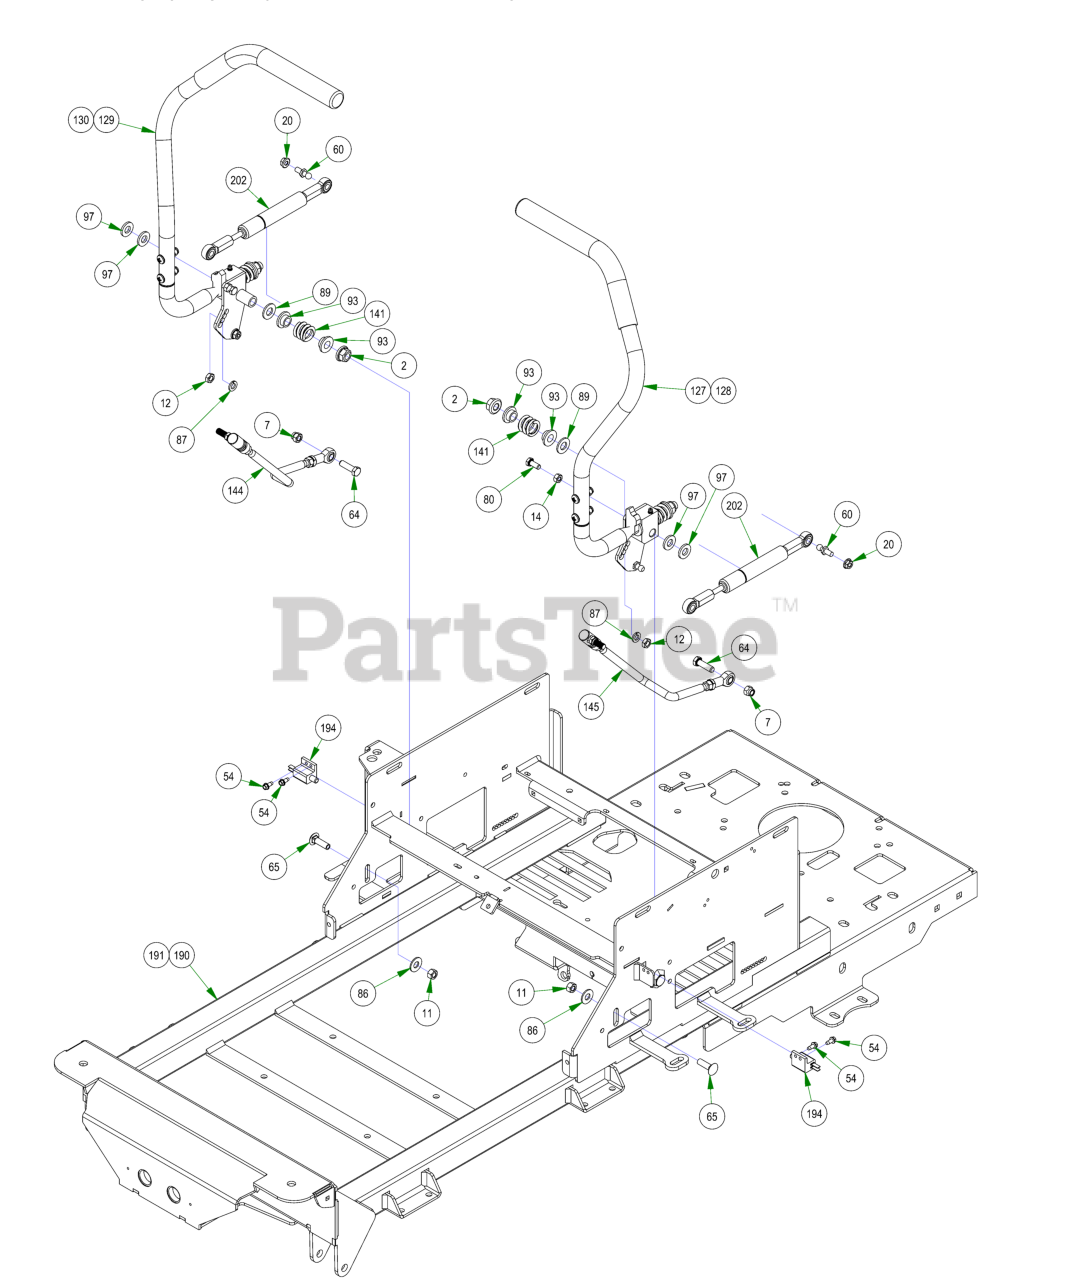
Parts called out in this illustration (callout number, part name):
2	1/2-13 HEX FLANGE AUTO OVAL LOCKNUT (GR.F) ZINC/WAX
7	3/8-16 NYLON INSERT LOCKNUT ZINC
11	3/8-16 HEX NUT ZINC
12	3/8-24 HEX NUT ZINC YELLOW
14	5/16-18 HEX NUT ZINC
20	5/16-18 HEX SERRATED FLANGE NUT HARD/ZINC
54	12-24 X 1/2 HEX WASHER UNLSOT F TCS ZINC
60	10mm Damper Ball Stud-XP Linkage
64	3/8-16 X 1-1/4 HEX CAP SCREW (GR.5) ZINC
65	3/8-16 X 1-1/4 CARRIAGE BOLT ZINC
80	5/16-18 X 3/4 HEX CAP SCREW (GR.5) ZINC
86	3/8 FLAT WASHER USS (1" OD) ZINC
87	3/8 SPLIT LOCKWASHER ZINC
89	1/2 SAE FLAT WASHER (1-1/16" OD) GR.8 ZINC YELLOW
93	.525 ID SHOULDER WASHER NYLON
97	.505 ID X 1.000 OD X .125 THICK FLAT WASHER NYLON
127	ZT Steering Arm Assembly, Left Hand
128	ZT Steering Arm Assembly, Left Hand
129	ZT Steering Arm Assembly-Right Hand
130	ZT Steering Arm Assembly-Right Hand
141	Drive Lever Spring
144	Push Rod-Right
145	Push Rod-Left
190	2023 ZT Elite Frame- Painted
191	2023 ZT Elite Frame- Painted
194	Safety Switch
202	Steering Damper
